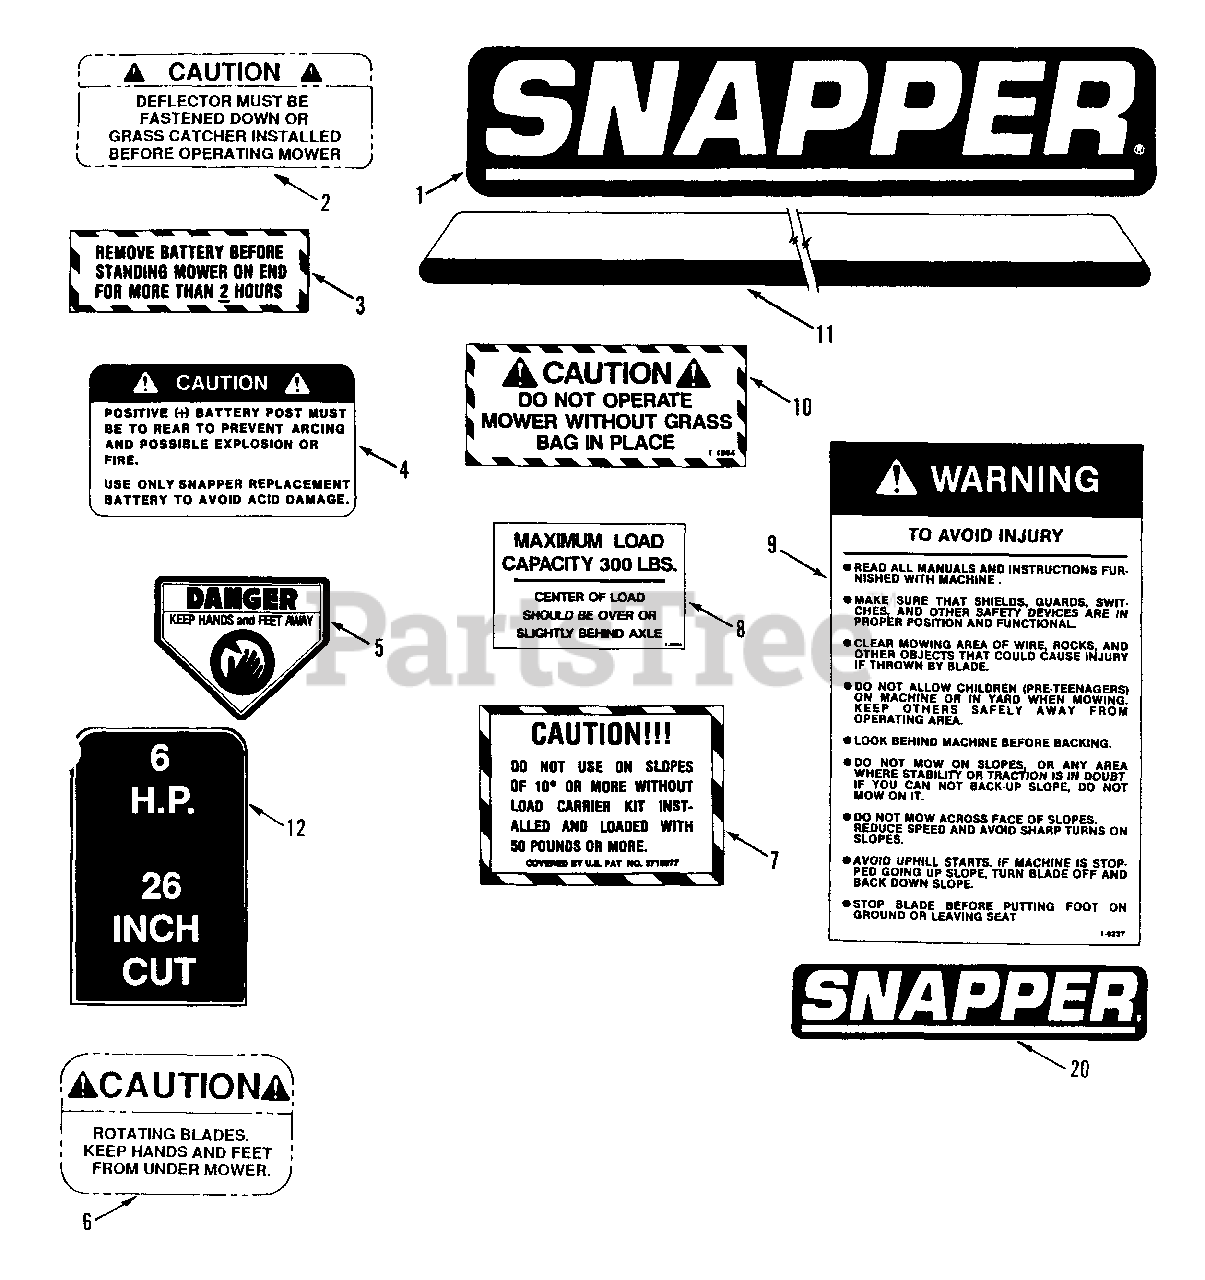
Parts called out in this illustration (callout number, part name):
1	LOGO, SNAPPER Molded 8"
2	DECAL, Caution, Deflector
3	DECAL, Battery
4	DECAL, Caution, Battery
5	DECAL, Danger
6	DECAL, Caution, Rotating Blades
7	DECAL, Caution, Carrier
8	DECAL, Maximum Capacity
9	DECAL, Warning, Instruction
10	DECAL, Caution, Grass Bag
11	DECAL, Stripe, Gray (Left)
12	DECAL, Model 6 HP, 26" Cut
20	LOGO, SNAPPER Molded, 4"
